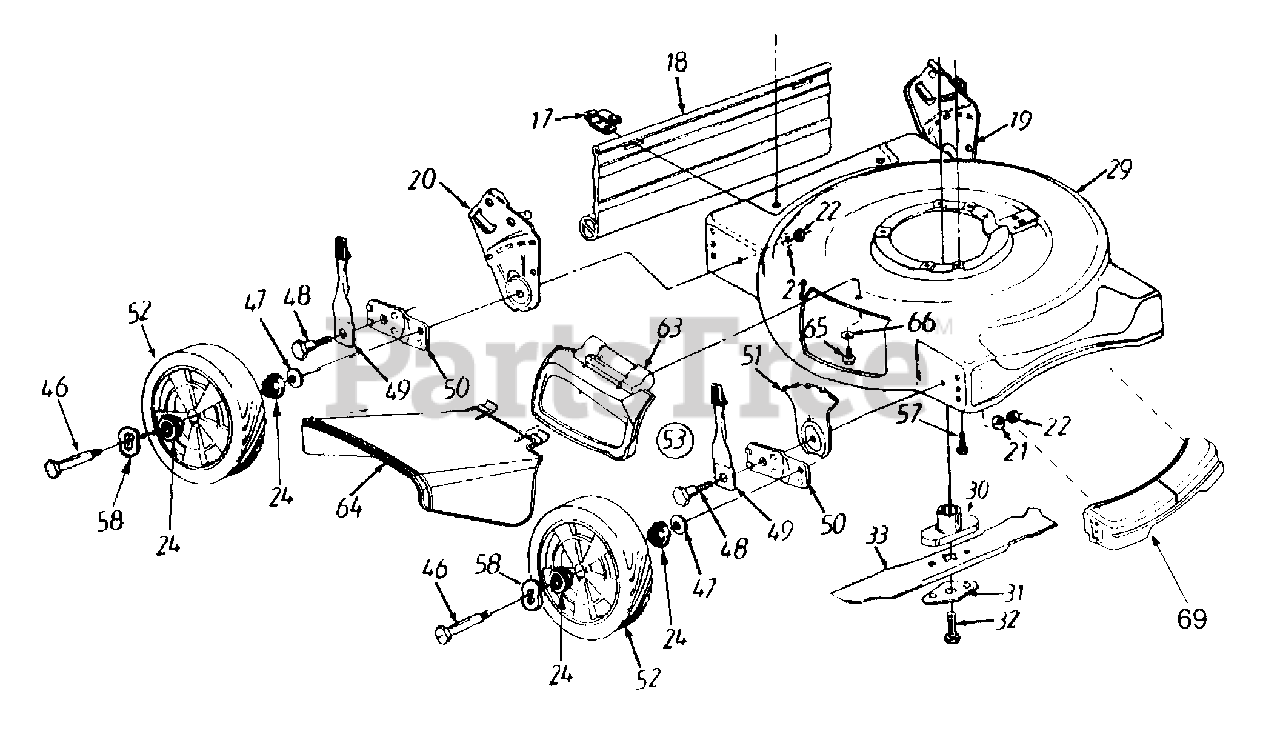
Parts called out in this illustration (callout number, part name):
17	Hinge Clip
18	Rear Flap
21	Bell Washer .39" ID x 1.38"
22	Hex Nut 3/8-16 Thd.
24	Bearing
29	Deck Assembly
30	Blade Adapter Kit
31	Blade Bell Support
32	Hex Bolt 7/16-20 x 1.5"
33	20" Mulch Blade
46	Axle Bolt
47	Bell Washer .400" ID x .88"
48	Shoulder Bolt
49	Spring Lever Ass'y w/Knob
51	Height Adj. Plate
52	Wheel Assembly
53	Height Adj. Ass'y. Comp. R.F. & L.R.
57	Hex Lock Wash. Hd. Screw 3/8-16 x 1.0" Lg.
58	Wave Washer
63	Mulching Plug
64	Chute Deflector
65	Bell Washer
66	Hex Wash. Hd. TT Screw 1/4-20 x .5" Lg.
69	Cover: Front End
